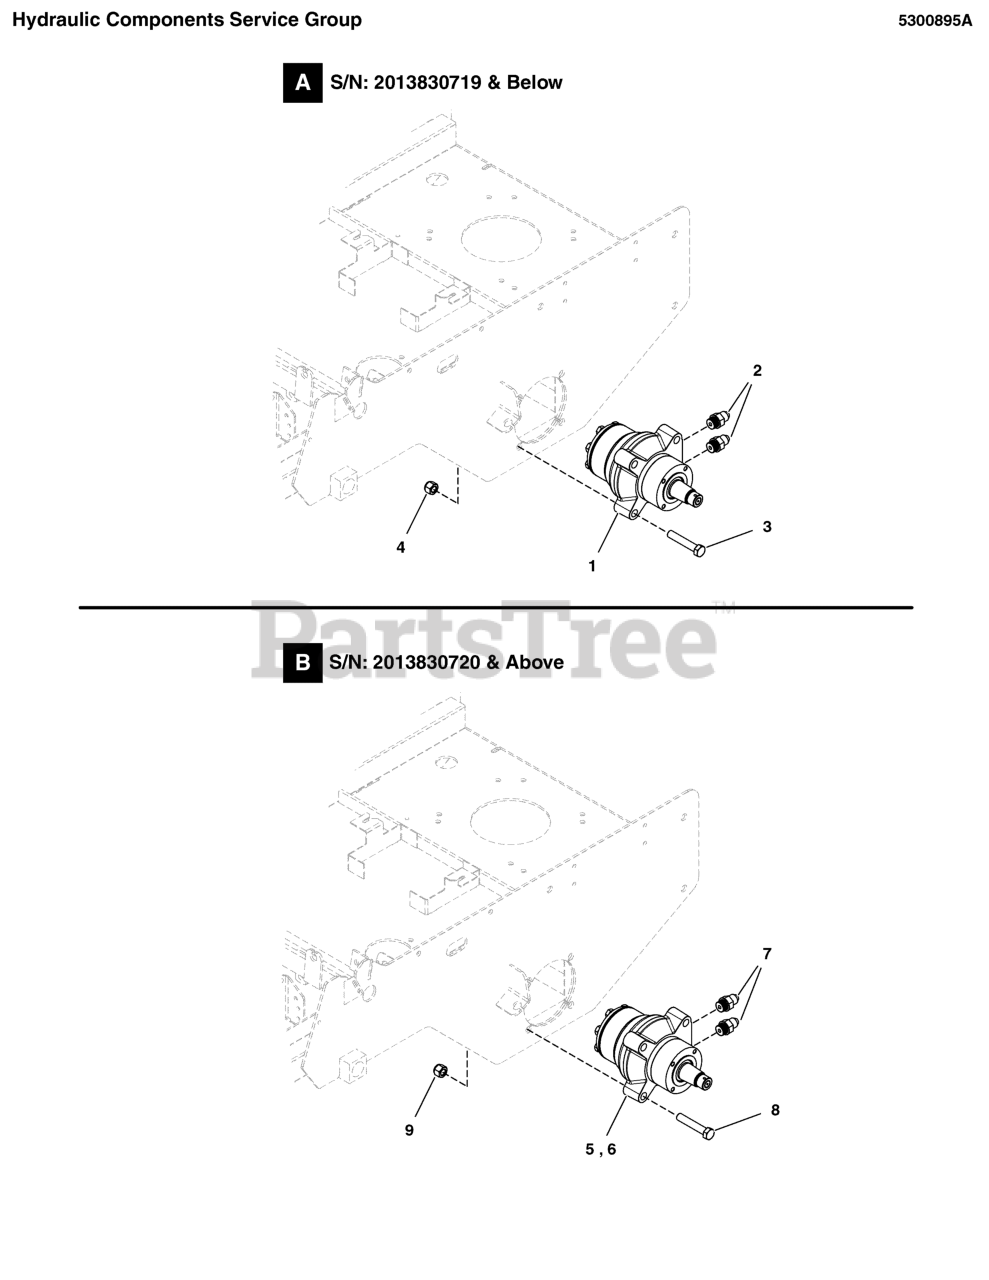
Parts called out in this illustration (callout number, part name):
2	FITTING, #8 O-RING X #8 JIC, STR
3	BOLT, 1/2-13 X 2-3/4 GD5 CZ
4	NUT, 1/2-13 HEX NYLON LOCK
5	WHEEL MOTOR, LH, 14.5 CI-TF0240LS080AAKZ
6	WHEEL MOTOR, RH, 14.5 CI-TF0240LS081AAKZ
7	FITTING, #10 O-RING X #8 JIC, STR
8	BOLT, 1/2-13 X 2-1/2, NYLON PATCH
9	NUT, 1/2-13 SQUARE
